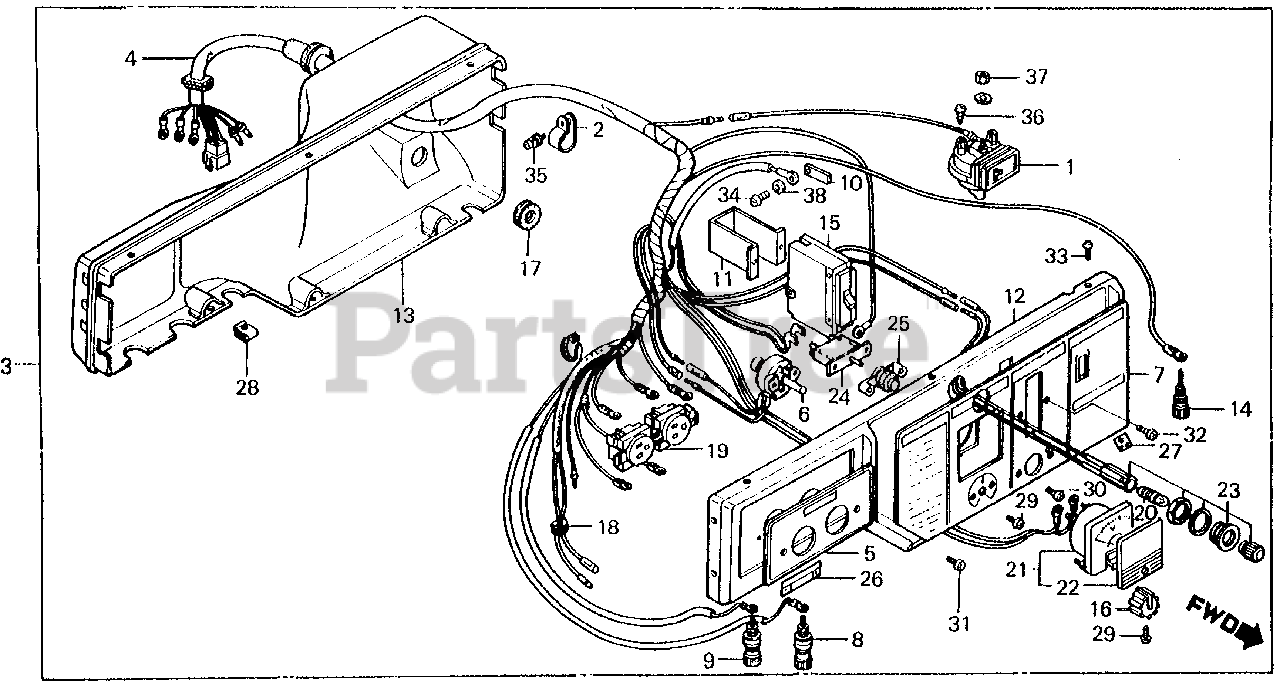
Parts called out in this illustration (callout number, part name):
1	SWITCH ASSY., UNIT
2	CLAMP, CABLE
3	BOX ASSY., CONTROL *R8* (BRIGHT RED)
4	WIRE HARNESS ASSY.
5	MARK, A.C. OUTPUT
6	RESISTOR, VARIABLE (NOT AVAILABLE)
7	MARK, SWITCH PANEL (NOT AVAILABLE)
8	TERMINAL, D.C. OUT (+)
9	TERMINAL, D.C. OUT (-)
10	TERMINAL, BREAKER
11	SUPPORT, BREAKER
12	PANEL, CONTROL *R8* (BRIGHT RED) (NOT AVAILABLE)
13	CASE, CONTROL
14	TERMINAL ASSY., GROUND
15	BREAKER, CIRCUIT (15A)
16	KNOB, ADJUSTING
17	GROMMET, UNIT SWITCH
18	GROMMET, SWITCH WIRE
19	RECEPTACLE (15A/125V)
20	BULB (24V2W)
21	VOLTMETER ASSY.
22	LENS, METER
23	SOCKET ASSY., PILOT LAMP
24	PROTECTOR, CIRCUIT (DC)
25	LENS ASSY., PROTECTOR
26	MARK, D.C. OUTPUT (NOT AVAILABLE)
27	MARK, GROUND
28	NUT, SPRING (5MM)
29	SCREW, PAN (3X6)
30	SCREW, PAN (3X12)
31	SCREW, PAN (4X6)
32	SCREW, PAN (4X6)
33	SCREW, PAN (5X10)
34	SCREW, PAN (5X12)
35	SCREW-WASHER (4X16)
36	SCREW, TAPPING (5X10)
37	NUT, HEX. (5MM)
38	WASHER, SPRING (5MM)
